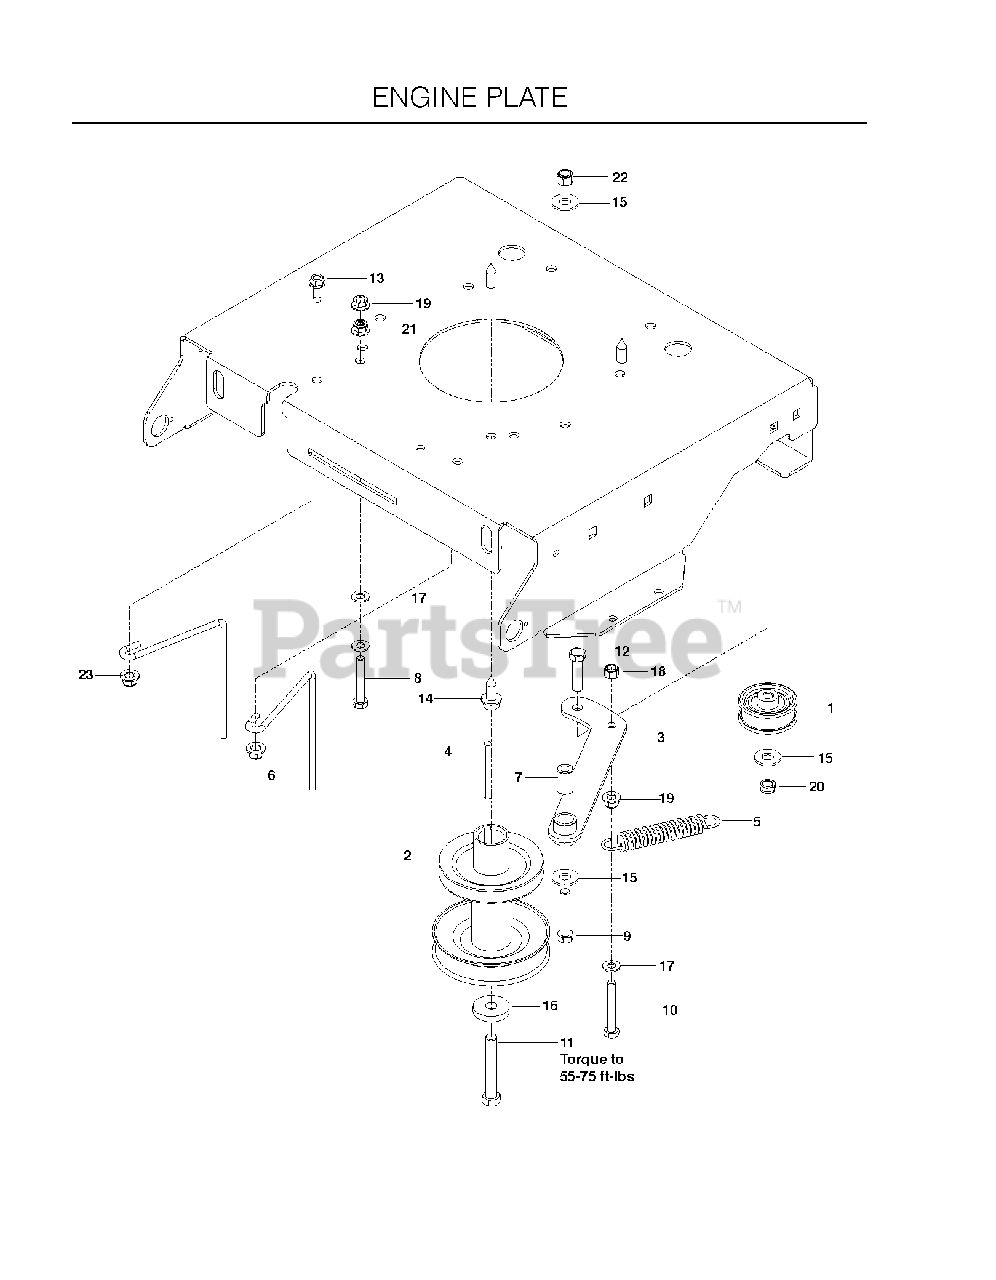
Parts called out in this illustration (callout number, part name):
1	PULLEY IDLER
2	PULLEY, ENGINE 30"
4	KEY 1/4 SQ X 2-1/2
5	SPRING - 3.50
6	BELT GUIDE
8	HCS 5/16-18X2
9	HCS 3/8C X 2
10	CAPSCREW
11	HCS 7/16-20 X 2-3/4
12	HCS 3/8C X 1 1/2
13	BOLT 3/8-16 X 1.0
14	HHFS 3/8-16 X 1.0 THD FORMING
15	WASHER 3/8 FLAT
16	WASHER .43X1.38X.25
17	FLAT WASHER 5/16 SAE
18	NUT 5/16 NYLOC
19	NUT 5/16C WHIZ
20	NUT HEX 3/8-16 NYLON, THIN
21	5/16-18 NYLOC FLANGE NUT
22	NUT 3/8-16 NYLOC
23	NUT 3/8-16 HEX FLG NYLOC ZD
